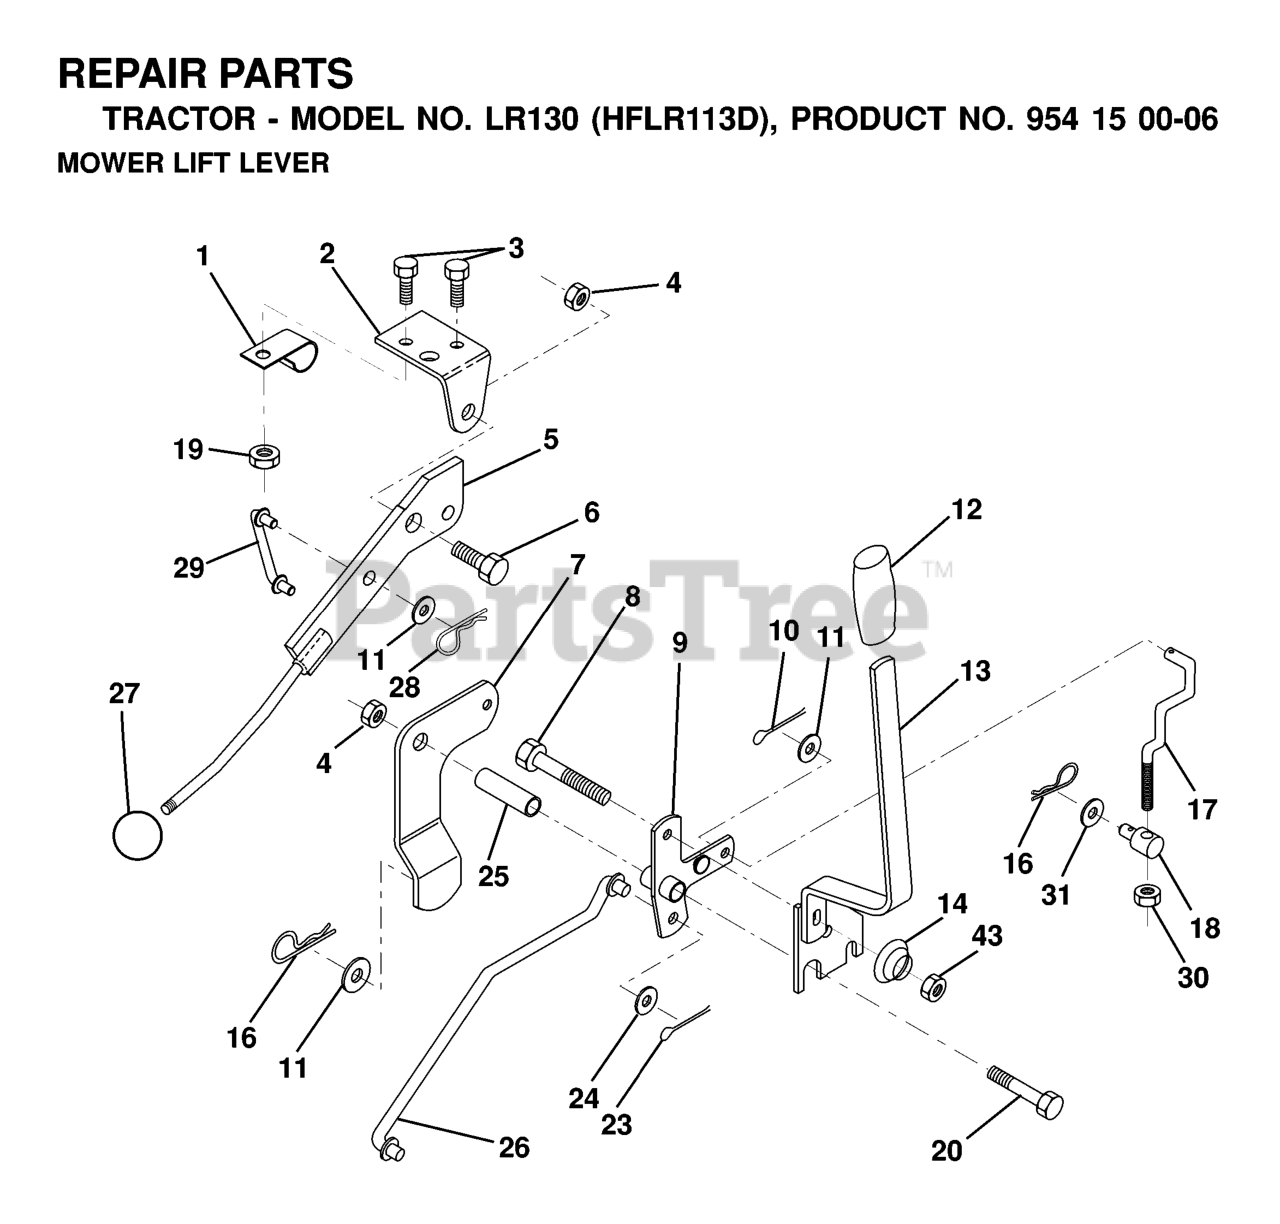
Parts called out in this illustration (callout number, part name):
1	CLIP,INSULATOR
2	BRKT CLUTCH
3	BOLT
5	CLUTCH LEVER
6	BOLT, SHOULDER LT
7	ASSEMBLY MOWER CLUTCH ARM
9	BELLCRANK,LIFT
10	COTTER PIN
11	WASHER
12	HANDLE GRIP
13	LIFT HANDLE ASSY
14	SPRING COMPRESSIO
16	SPRING TI
17	LINK LIFT FRT
18	TRUNNION.ADJUSTABLE.3/8-16
19	Nut, Keps Blk Hex 1/4-20 UNC
23	PIN COTTER
24	WASHER GT
25	TUBE SPACER
27	KNOB T (3/8 HOLE)
28	RETAINER M
29	LINK MOWER CLUTCH
30	NUT
31	WASHER
43	NUT LOCK FLG 3/8-16 UNC
